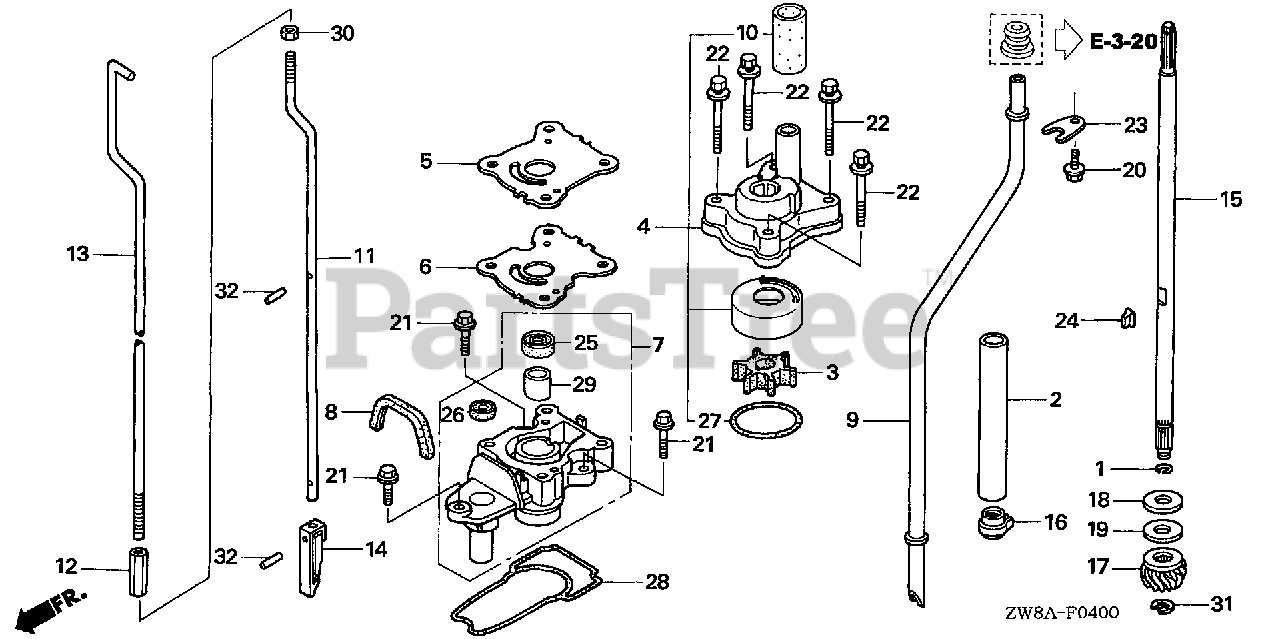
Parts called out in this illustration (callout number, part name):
1	CLIP, VALVE GUIDE
2	GUIDE, OIL (S,L)
3	IMPELLER, PUMP (S,L)
4	HOUSING ASSY., IMPELLER
5	COVER, IMPELLER
6	GASKET, IMPELLER
7	HOUSING, WATER PUMP (S,L)
8	GROMMET, WATER PUMP HOUSING
9	TUBE, WATER (L)
10	RING, WATER TUBE SEAL
11	ROD B, SHIFT (L)
12	JOINT, SHIFT ROD
13	ROD A, SHIFT (L)
14	ROD, PUSH
15	SHAFT, VERTICAL (L)
16	SLINGER, OIL (S,L)
17	GEAR, PINION
18	WASHER A, THRUST BEARING
19	WASHER B, THRUST BEARING
19	WASHER C, THRUST BEARING
20	BOLT, FLANGE (6X12)
21	BOLT, FLANGE (6X20)
22	BOLT-WASHER (6X50)
23	PLATE, WATER TUBE SETTING
24	KEY, WOODRUFF
25	SEAL, WATER (13MM) (ARAI)
26	SEAL, WATER (6MM)
27	O-RING (42.2X2.4)
28	O-RING, WATER PUMP HOUSING
29	BUSH (13X15X15)
30	NUT, HEX. (6MM)
31	E-RING (8MM)
32	ROLLER (2.5X11.8)
